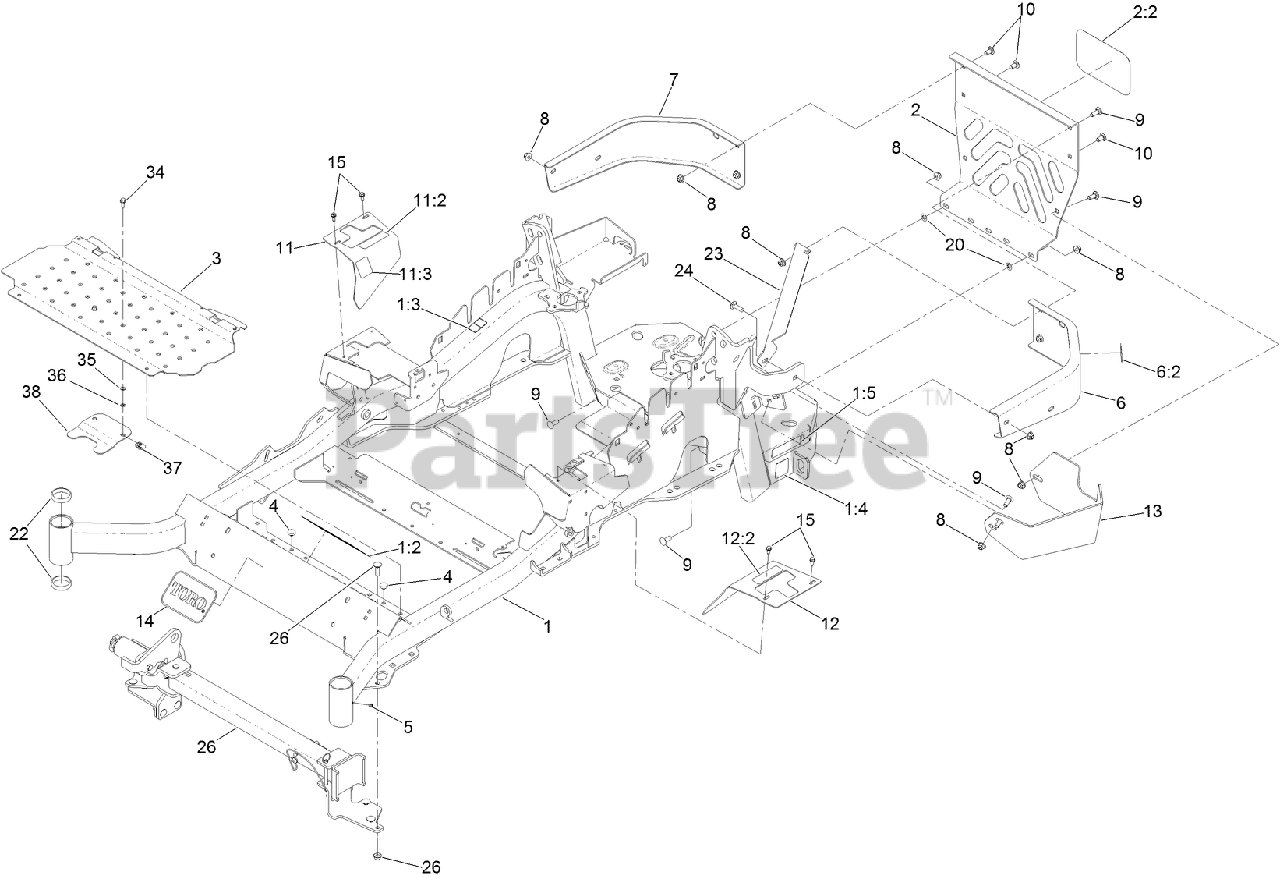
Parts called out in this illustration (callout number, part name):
1	MAINFRAME ASM
1:2	DECAL-DANGER
1:3	DECAL-WARNING
1:4	DECAL-HAZARD, PINCHED FINGER
1:5	DECAL-ARRESTOR, SPARK
2	REAR GUARD ASM
2:2	DECAL
3	FLOORPAN
4	BUMPER
6	LH BUMPER ASM
6:2	DECAL-WARNING
7	BUMPER-RH
8	NUT-HF, NI
9	SCREW-CARR
10	SCREW-CARR
11	RH MOTION CONTROL COVER ASM
11:2	DECAL-CONTROL, MOTION
11:3	DECAL-PARK BRAKE, CE
12	LH MOTION CONTROL COVER ASM
12:2	DECAL-CONTROL, MOTION
13	GUARD-MUFFLER
14	DECAL
15	SCREW-HWH
20	NUT-PUSH
22	CUP-BEARING
24	BOLT-CARR
26	Z STAND ASM
34	SCREW-HH
35	WASHER-FLAT
36	NUT-RETAINER
38	ADAPTER-CAPTIVE
